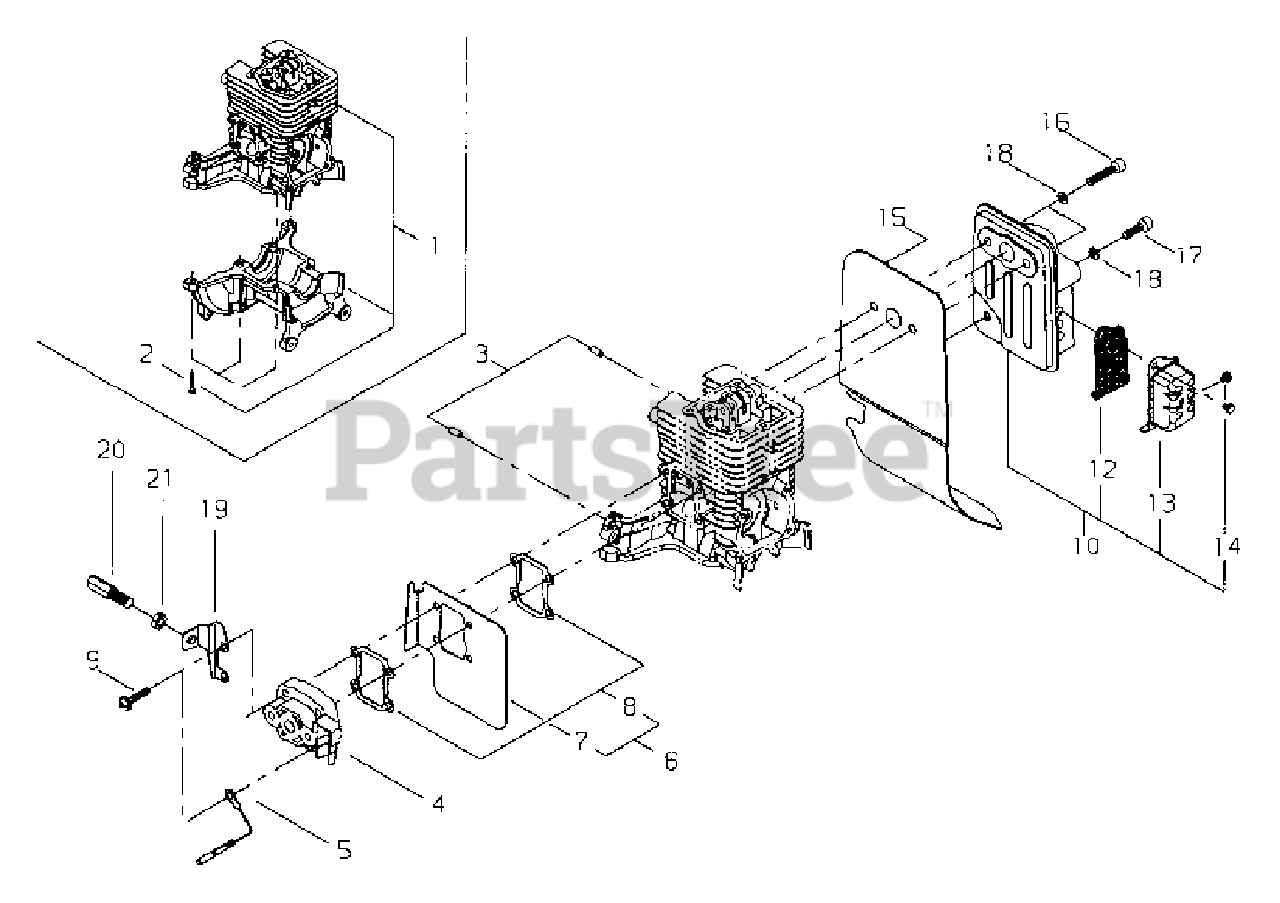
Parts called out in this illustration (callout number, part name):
1	CYLINDER BLOCK SET
2	SCREW - 5X16
3	PIN - LOCATING
4	INSULATOR
5	LEAD - GROUND
6	HEAT DEFLECTOR ASSY
7	DEFLECTOR, HEAT
8	SHIELD, INTAKE
9	SCREW - 5X22
10	MUFFLER ASSY
12	SCREEN, SPARK ARRESTOR
13	GUIDE, EXHAUST
14	SCREW - 4X6
15	SHIELD, EXHAUST
16	SCREW - 5X25
17	SCREW - 5X16
18	WASHER - 5
19	BRACKET, THROTTLE CABLE
20	NUT, CABLE ADJUST
21	LOCKNUT - 6
